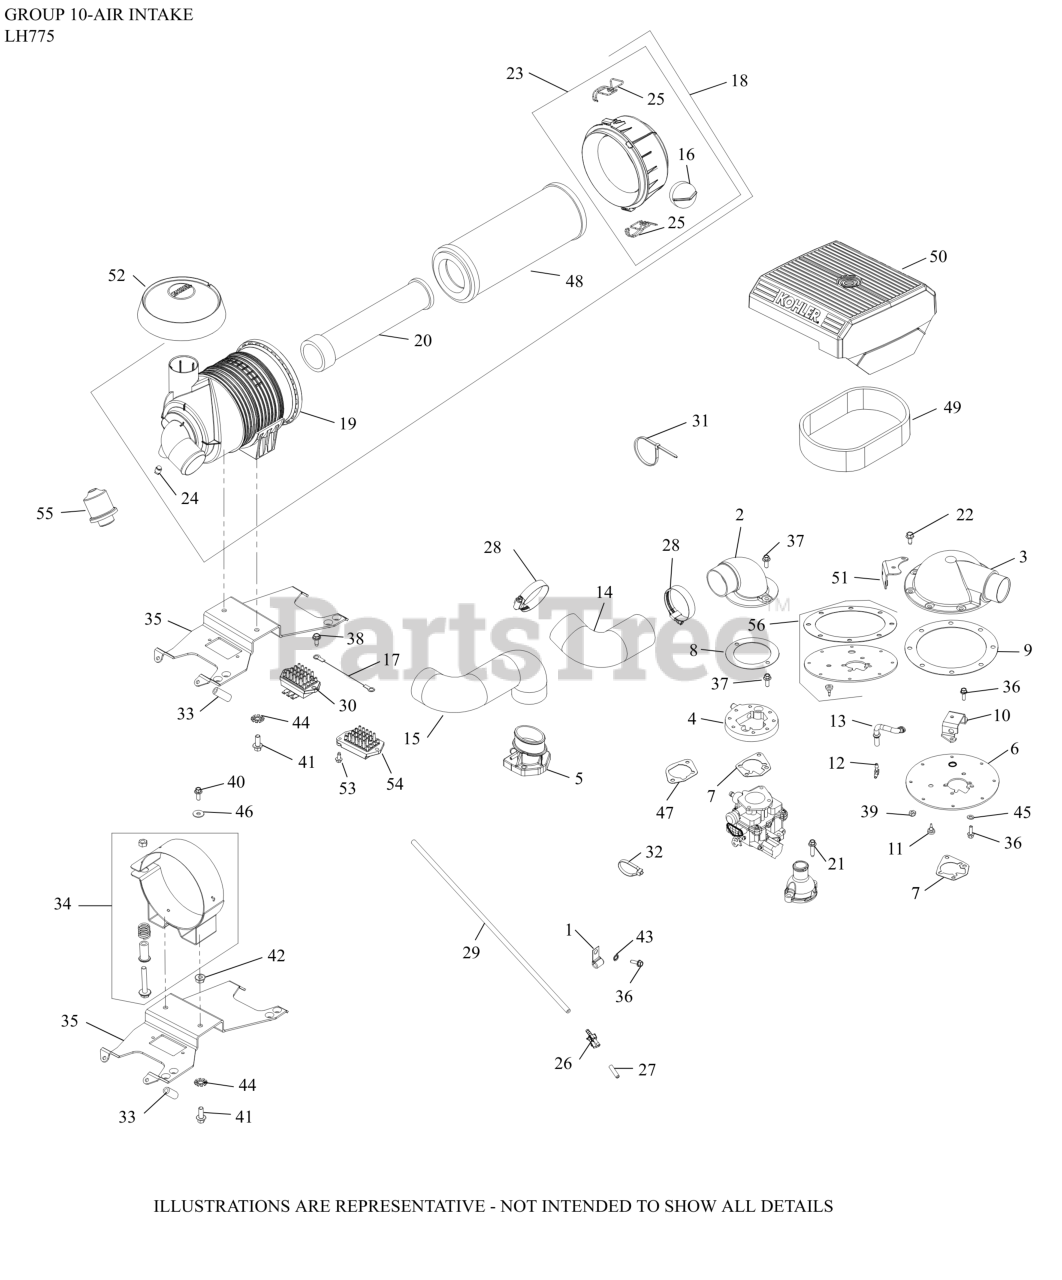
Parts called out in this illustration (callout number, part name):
2	ADAPTER, REMOTE AIR CLEANER
4	ADAPTER ASSY-USE 24 029 97-S
7	GASKET, AIR CLEANER BASE
8	GASKET, ADAPTER
16	VALVE, DUST EJECTOR
18	AIR CLEANER ASSY-USE 25 048 17-S
19	HOUSING, HD AIR CLEANER
20	ELEMENT, AIR FILTER - SAFETY
23	COVER ASSEMBLY, AIR CLEANER
24	PLUG, PIPE
30	REGULATOR, RECTIFIER-USE 25 403 32-S
37	SCREW, FLG M6X1.0X16
48	ELEMENT, AIR FILTER - PRIMARY
NI	BRACKET, AIR CLEANER-USE 24 126 191-S
NI	CLIP ASSEMBLY
